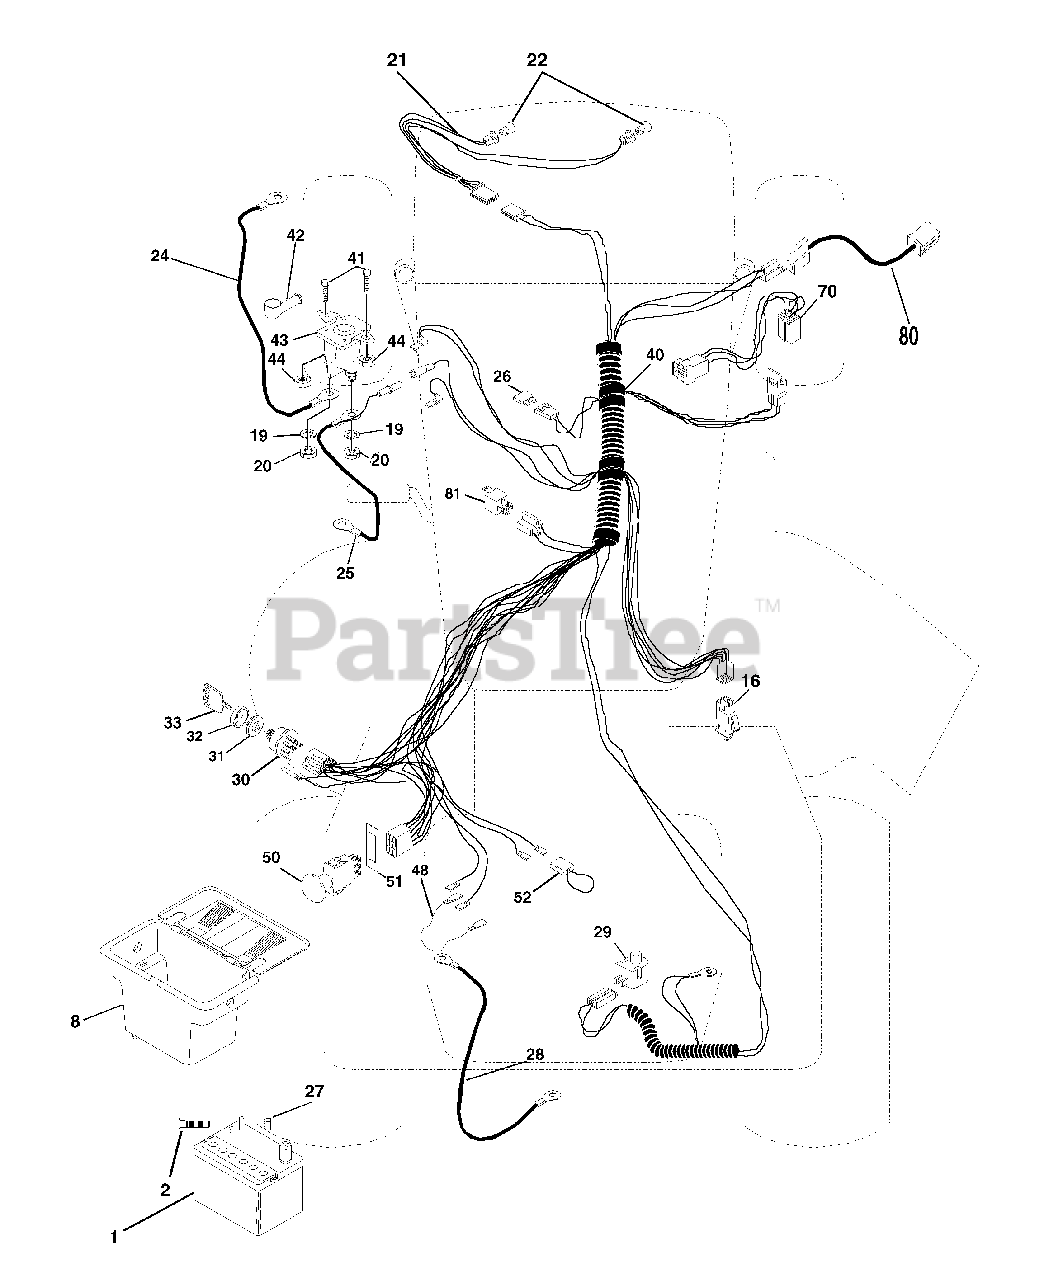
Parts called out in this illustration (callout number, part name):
1	Battery 12 Volt 25 AMP
2	Bolt Hex Hd 1/4-20unc x 3/4
8	Case Battery Mech Hinge
16	Switch Interlock Push-In
19	Washer Lock 1/4
20	Nut Jam Hex 1/4-20 Unc
21	Harness Asm Light W/4152j
22	Bulb Light #1156
24	Cable Battery 6 Ga 11" red
25	Cable Battery 6 Ga 44" red w/16 wire
26	Fuse 30 AMP Auto Green
27	Nut Keps Hex 1/4-20 Unc
28	Cable Ground 6 Ga 12" black
29	Switch Plunger Normal OP Olive
30	Switch Ign 4 pos w/lights
31	Nut Ignition
32	Cover Sw Ignition
33	Key Ign Molded Indak
40	Harness Ign.
41	Bolt Blk Fin Hex 1/4 - 20 x 1/2
42	Cover Terminal Red
43	Solenoid
44	Nut Keps Hex 1/4-20 Unc
48	Adapter Ammeter Rectangular
50	Switch PTO 3PDT Black Delta 96
51	Ring Retainer PTO
52	Protection Wire Loop
70	Harness, Eng. kohl Cmd-L
80	Harness Clutch EVX
